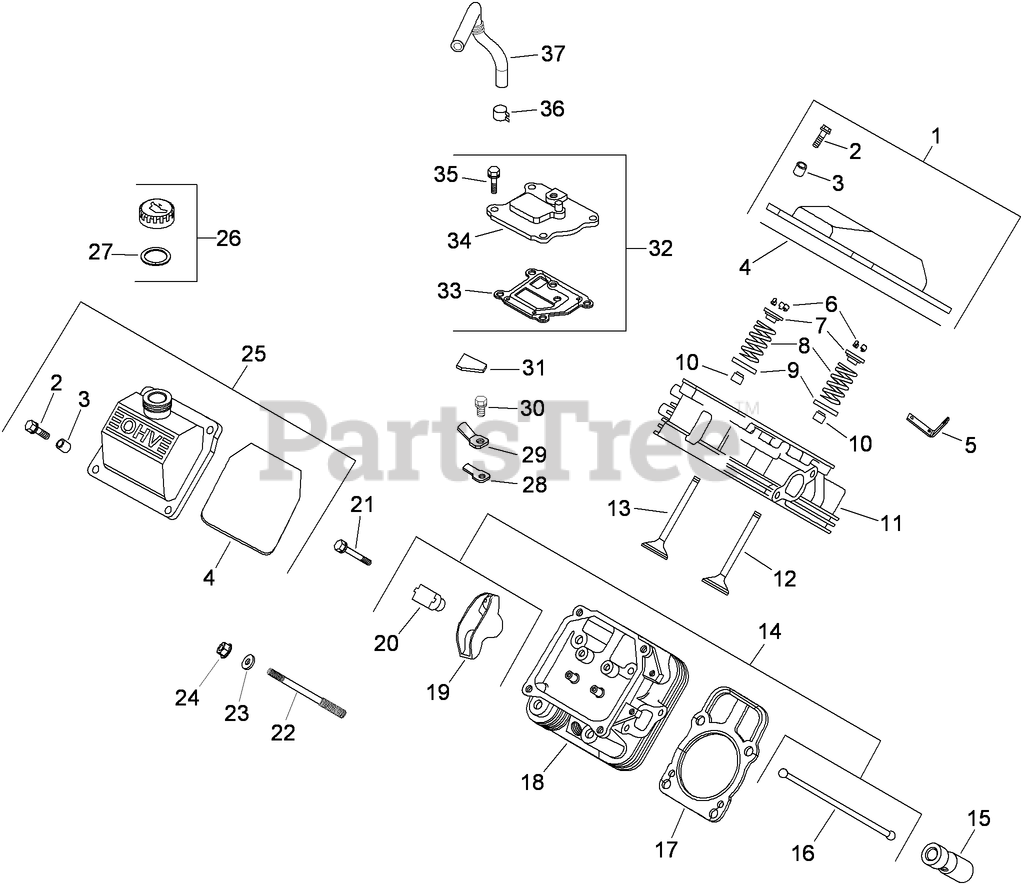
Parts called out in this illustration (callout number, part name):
1	Plain Valve Cover Kit (Includes Ref 2-4)
2	SCREW-FLANGE (M6X1.0X30)
3	Spacer
4	O-Ring
5	STRAP-LIFTING
6	RETAINER KIT
7	CAP-SPRING, VALVE
8	SPRING-VALVE
9	RETAINER-SPRING
10	SEAL-STEM, VALVE
11	No. 1 Cylinder Head ASM
12	VALVE-INTAKE (STD)
12	VALVE-INTAKE (.25)
13	VALVE-EXHAUST (STD)
13	VALVE-EXHAUST (.25)
14	VALVE TRAIN KIT (Includes Ref 16, 19, 20)
15	Lifter-Valve
16	ROD-PUSH
17	Gasket-Cylinder Head
18	No. 2 Cylinder Head ASM
19	ARM-ROCKER
20	Pivot-Arm, Rocker
21	SCREW-FLANGE (M6X1.0X34)
22	STUD (M8X1.25xM10X1.5x105MM) (cylinder head)
23	WASHER-FLAT (8.6 MM)
24	NUT-FLANGE (M8X1.25)
25	Oil Fill Valve Cover Kit (Includes Ref 2-4)
26	OIL FILL CAP KIT (YELLOW) (Includes Ref 27)
27	O-RING (OIL FILL CAP)
28	REED-BREATHER
29	Retainer-Reed, Breather
30	SCREW-HHFTF (M5X.80X10)
31	Filter-Breather
32	BREATHER ASM (Includes Ref 33-35)
33	Gasket-Breather
34	COVER-BREATHER
35	SCREW-HHFTF (M6X1.0X20)
36	Clamp-Hose
37	Hose-Breather
